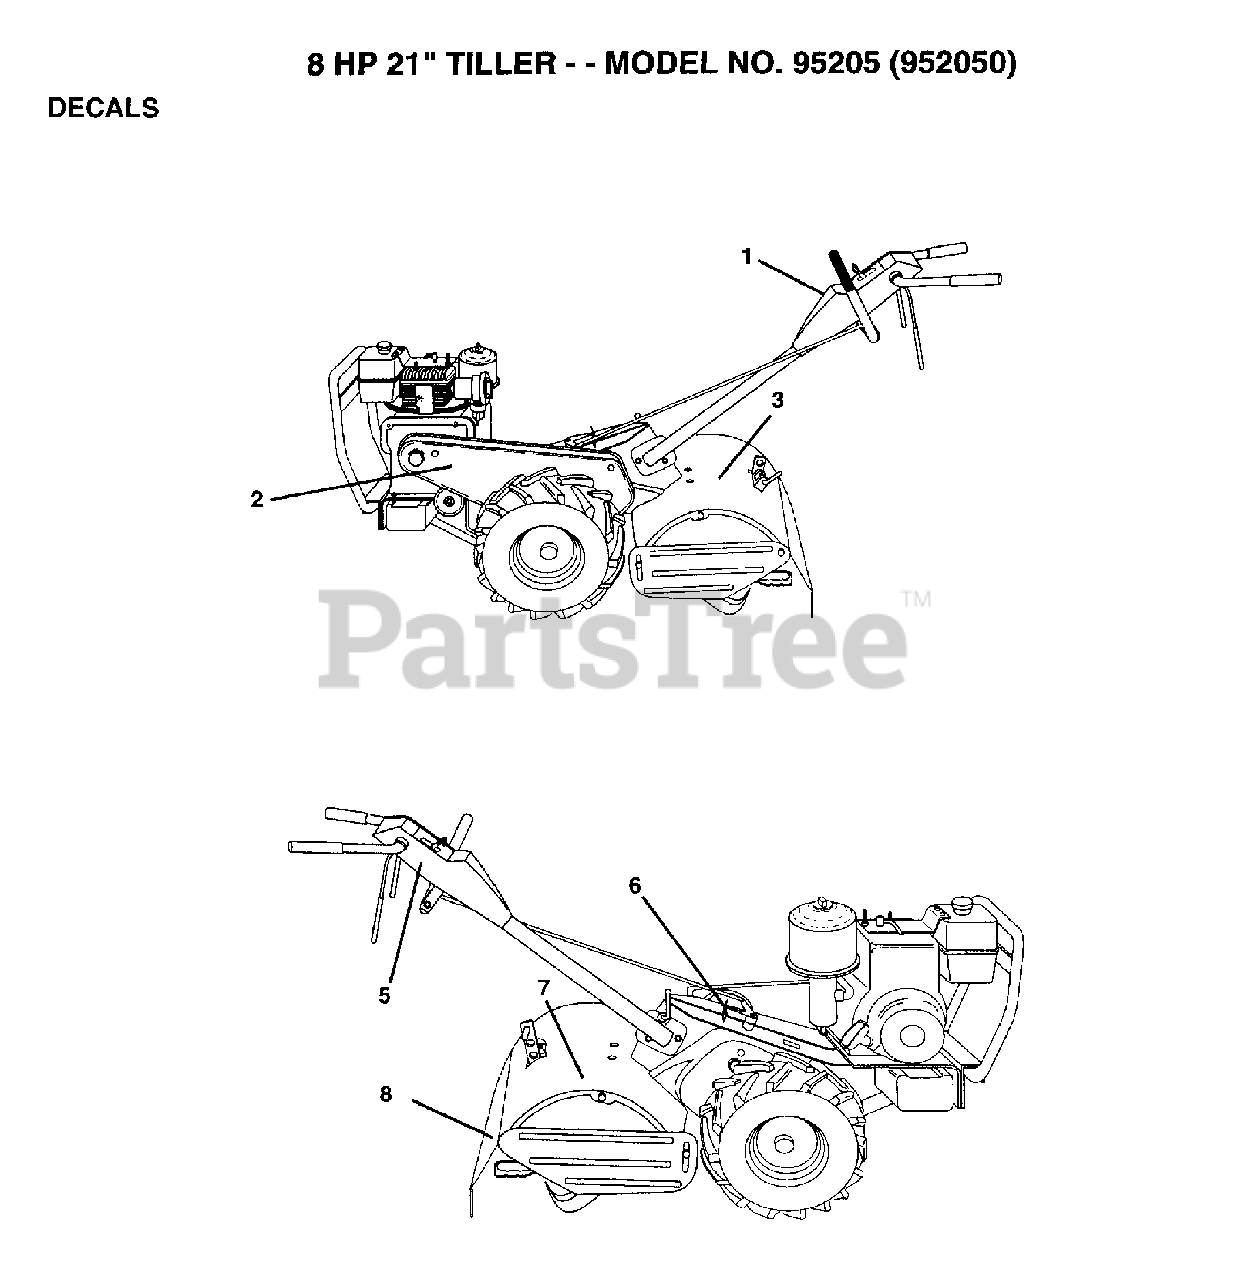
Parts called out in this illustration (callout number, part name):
1	DECAL.PANEL.CONTR
2	DECAL.GUARD.BELT
3	DECAL.SHLD.TINE.
4	DECAL.INSTRUCTION
5	DECAL TI
6	DECAL.SHIFT.IND.
8	DECAL TI
